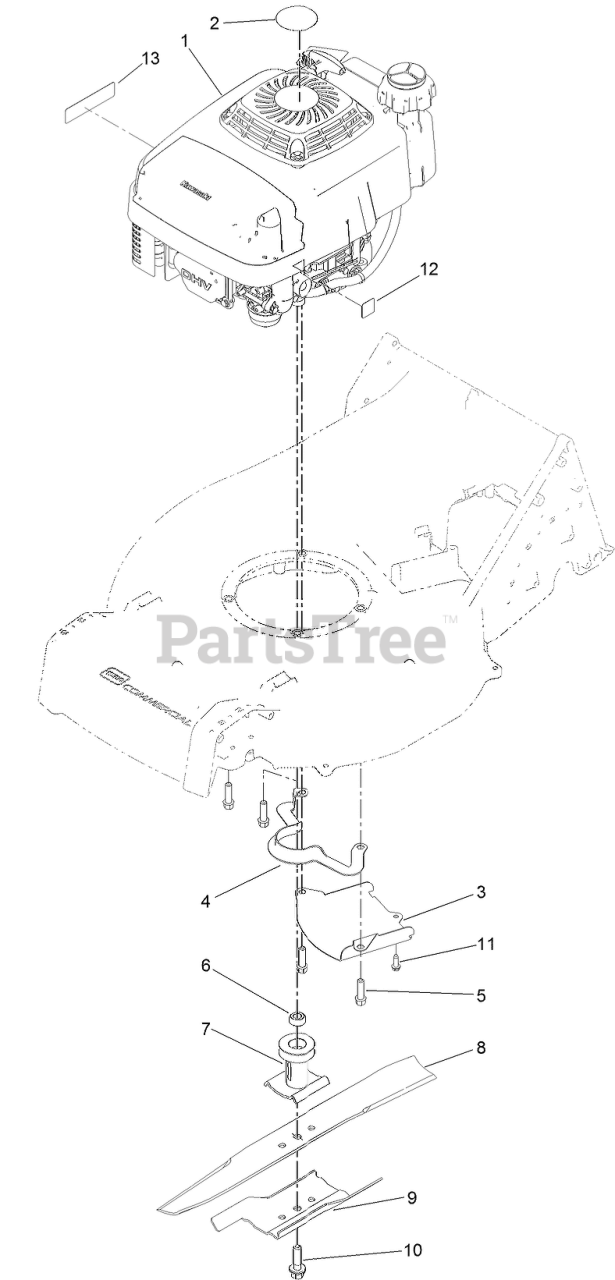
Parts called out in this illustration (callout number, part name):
1	ENGINE-KAWASAKI, FJ180V
3	SHIELD-GRASS
4	GUIDE-BELT
5	SCREW-TAPTITE
6	SPACER-DRIVER, BLADE
7	DRIVER-BLADE
8	BLADE-RECYCLING
9	ACCELERATOR-BLADE
10	BOLT-BLADE
11	SCREW-HWHTF
12	DECAL-PRIMER
13	DECAL-ARRESTER, SPARK
